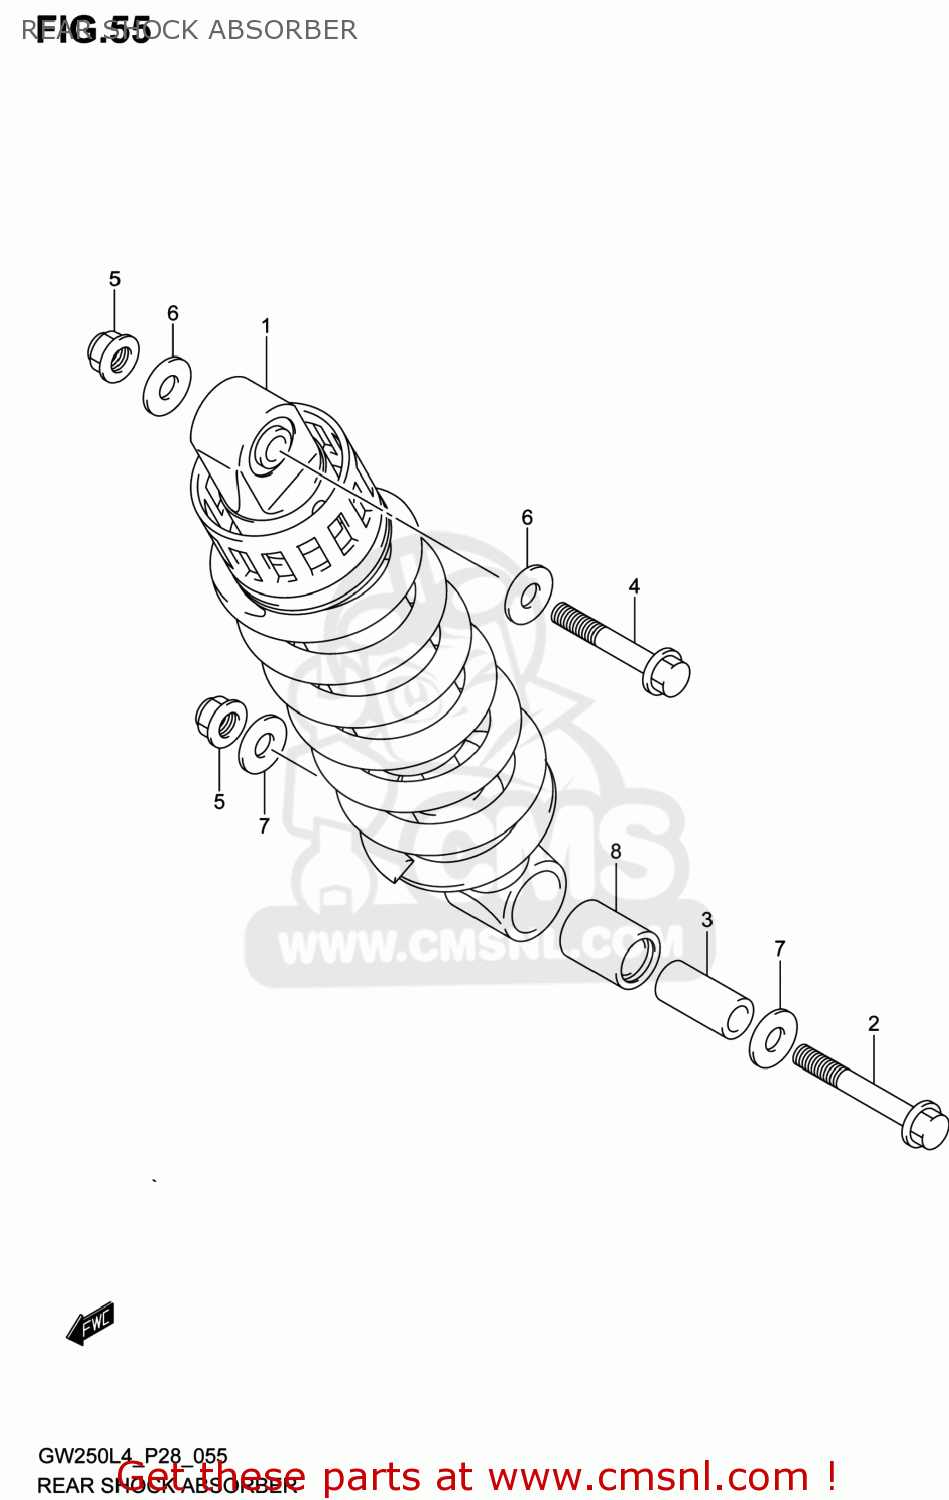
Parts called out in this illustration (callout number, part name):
1	ABSORBER ASSY,RR SHOCK
2	BOLT,RR SHOCK ABSORBER LWR
3	SPACER,RR SHOCK ABS LWR
4	BOLT(10X52)
5	NUT
6	WASHER(10.5X24X1)
7	WASHER(10.5X24X2.3)
8	BEARING(17X24X32)
